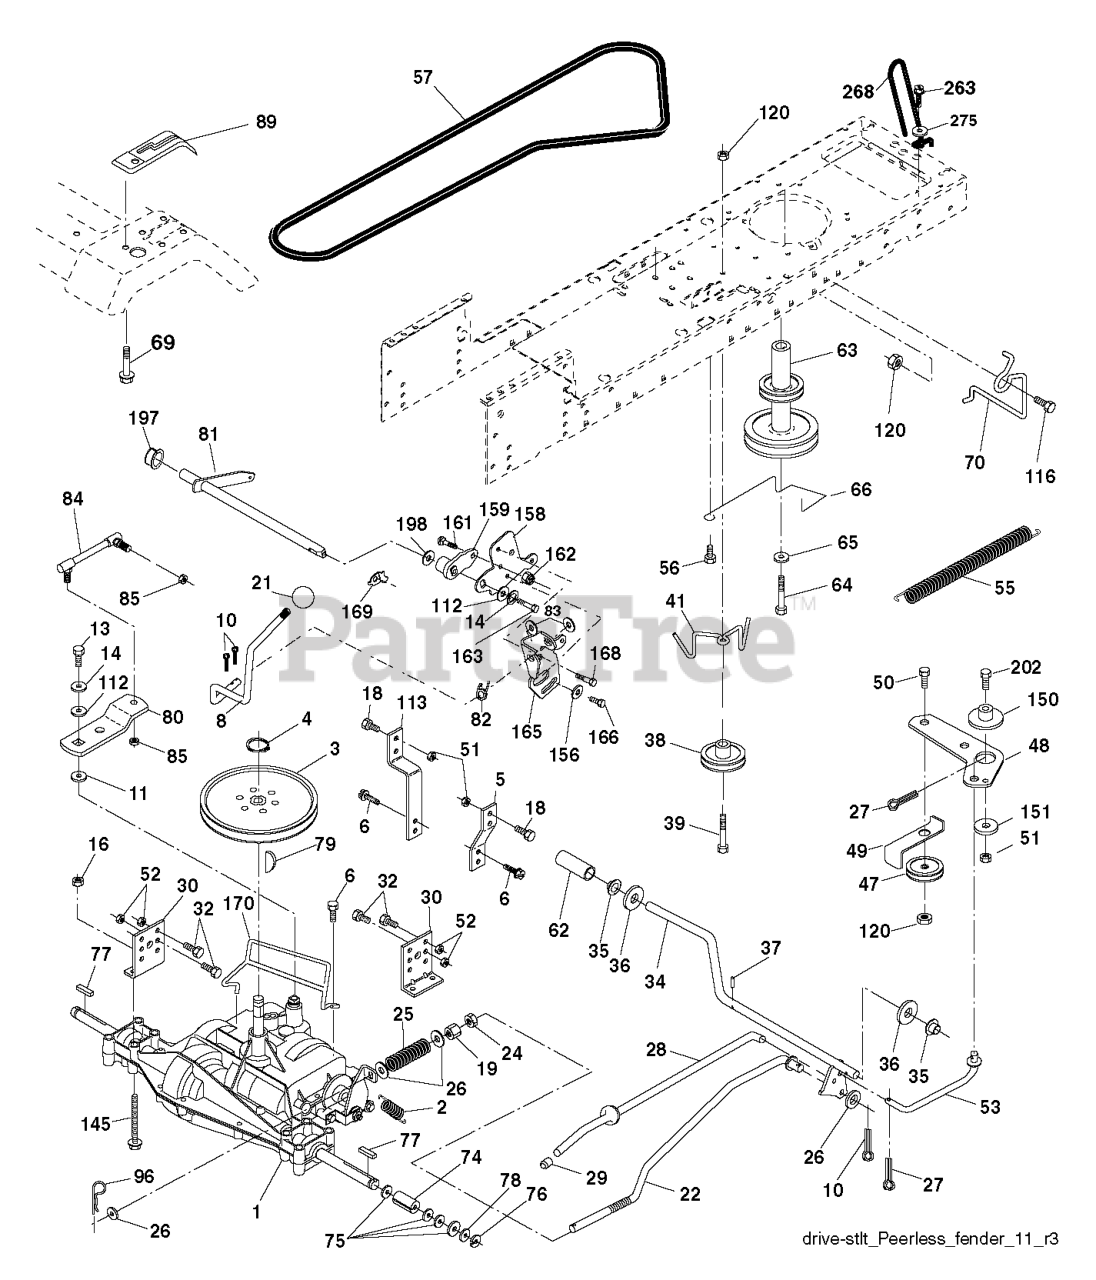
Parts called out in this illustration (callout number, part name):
2	SPRING,BRAKE RETURN
3	PULLEY TRANS
4	RETAINING RING LT
5	STRAP TORQUE
6	SCREW 5/16"
8	ROD SHIFT FENDER ADJUST LT
10	PIN COTTER
11	WASH-SHFT PLT LT
13	BOLT 1/4-28X3/4
14	LOCKWASHER
16	NUT.71038.31-18.HEX.NYLOCK
18	BOLT
19	NUT
21	KNOB T (1/2-HOLE)
24	NUT
25	SPRING ROD LT
26	WASHER
27	COTTER PIN
28	ROD, PARKING BRAKE
29	PLUNGER CAP
30	BRKT, MOUNT TRNSAXLE
32	BOLT
34	SHAFT, FOOT PEDAL
35	BEARING.NYLON
36	WASHER LT
37	DRIVE PIN
38	PULLEY IDLER COMPOSITE
41	KEEPER, BELT IDLER
47	IDLER PULLEY
48	BELLCRANK, CLUTCH
49	RETAIN BELT
50	BOLT.3/8-16X1.50
52	LOCKNUT
53	LINK.CLUTCH.7.66.2005
55	SPRING, RETURN LT
56	SCREW.3/8-16
57	BELT, V GROUND DRIVE 95 25
62	PEDAL COVER T
63	ENGINE PULLEY
64	BOLT HEX 7/16-20X4-1/4"
65	LOCKWASHER
66	KEEPER BELT ENGINE
69	SCREW.HI-LO.CONSOLE
70	KEEPER BELT ENG
74	SPACER AXLE
77	SQUARE KEY
79	KEY STD (1373) DANA
81	SHAFT ASM CROSS TAPERED
82	SHIFT SPRING
83	WASHER
84	LINK.TRNSAXLE
85	NUT LOCK CENTER 1/4 -28 FNTHD
89	CONSOLE SHIFT STLT
96	RETAINER M
112	WASHER LT
113	STRAP TORQUE LH LT
116	BOLT D
120	NUT LOCK FLG 3/8-16 UNC
145	BOLT
150	SPACER, RETAINER
151	WASHER 12/32X2X10GA
156	WASHER.SRRTD.5/16
158	BRACKET.SHIFT.MOUNT
161	BOLT
162	NUT.CROWNLOCK.1/4
163	BOLT
165	BRACKET.PIVOT.LEVER
166	CAPSCREW.HXHD.FLG.5/16-18X.625
168	BOLT.SHOULDER.5/16-18X
169	PLATE.FASTENING.CROSS.SHAFT
170	KEEPER BELT T/A
197	NYLINER SNAP 5/8" ID
198	WASHER.NYL.7/8IDX.105"HYD CR
263	SCREW, 3/8-16X3/4
268	GUARD MUFFLER
275	WASHER
